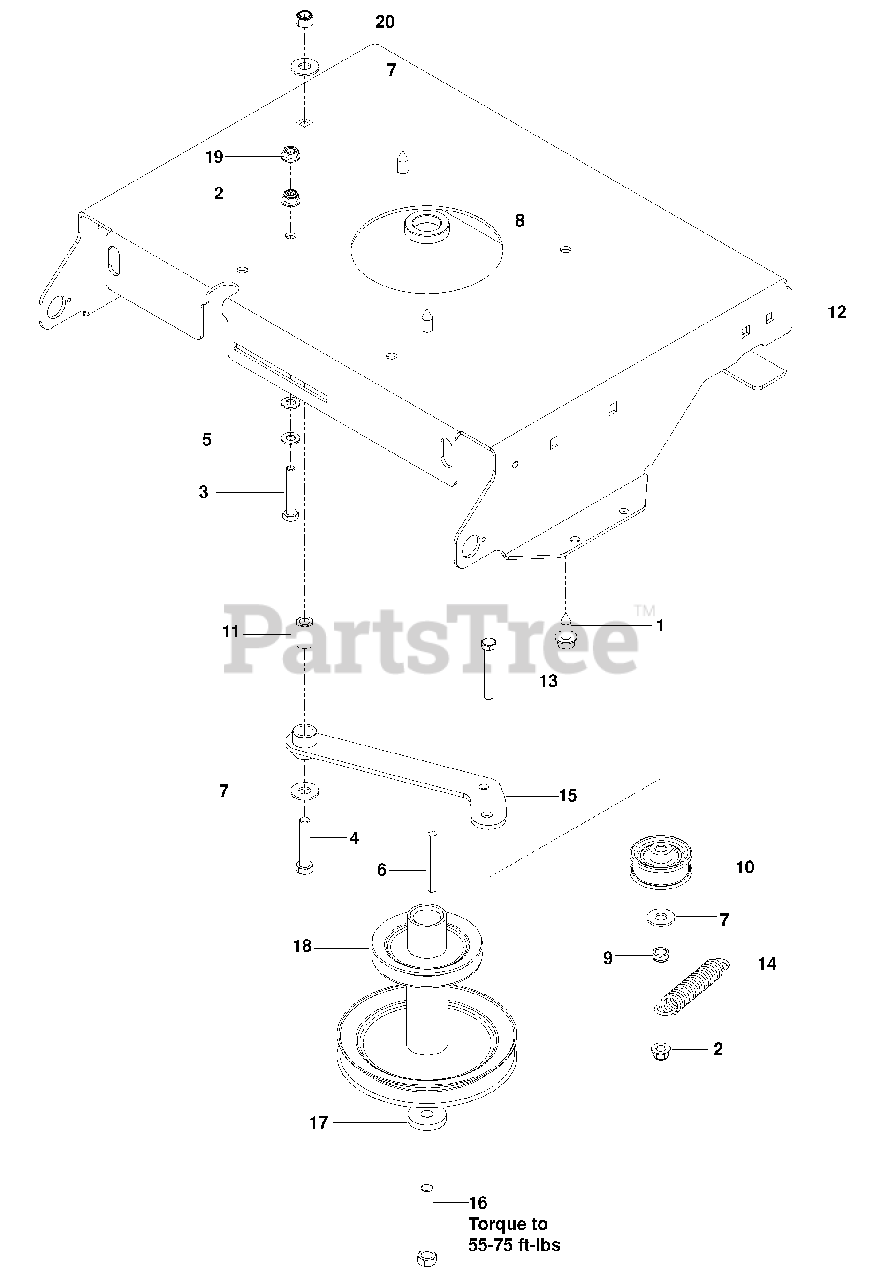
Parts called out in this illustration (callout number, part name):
1	HHFS 3/8-16 x 1 THD FRM
2	NUT 5/16-18 FLANGE NYLOC
3	HCS 5/16-18 x 2
4	HCS 3/8-16 x 2
5	WASHER 5/16 SAE FLAT
6	KEY 1/4 SQ x 2 1/2 LG
7	WASHER 3/8 FLAT STD
9	NUT 3/8-16 HEX JAM NYLOC
10	PULLEY, IDLER
11	BUSHING, METAL
12	PLATE, ENGINE
13	HCS 5/16-18 x 2 1/4
14	SPRING 3 1/2
16	HCS 7/16-20 x 3
18	PULLEY, ENGINE
19	NUT 5/16-18 HEX WHIZLK
20	NUT 3/8-16 HEX NYLOC
